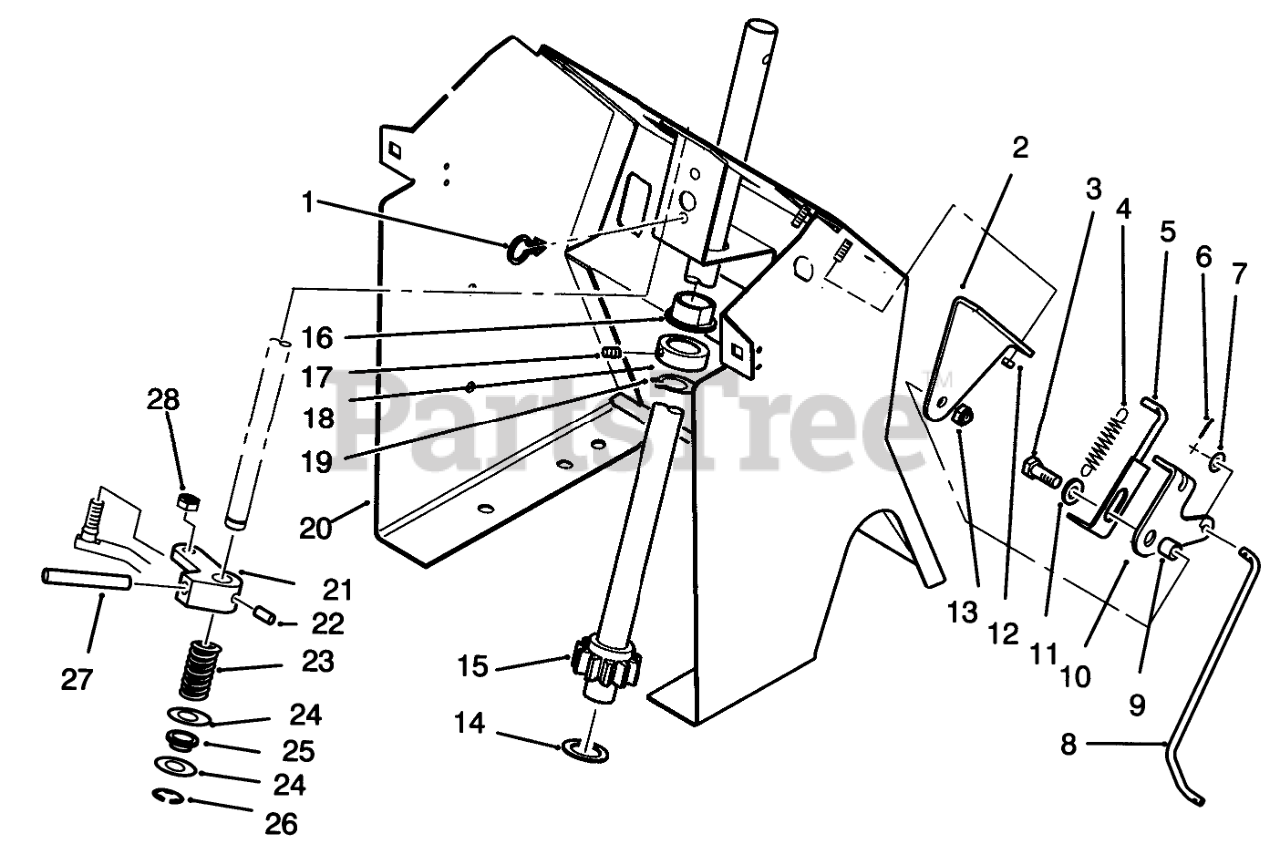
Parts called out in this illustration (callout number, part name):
1	CLIP-SNAP IN
2	SUPPORT-INDICATOR B
3	Bolt
4	SPRING-EXTENSION
5	WLDMT-INDICATOR R
6	Cotter Pin
7	WASHER-PLAIN
8	ROD-INDICATOR
9	SPACER
10	RETAINER-INDICATO B
11	WASHER-FLAT
12	Nut
13	NUT-LOCK, NI
14	WASHER
15	WLDMT-STRG SHAFT
16	BEARING-FLANGED
17	SCREW-HSH
18	COLLAR
19	RING-RETAINING
20	HOODSTAND W/A B
21	ARM-SPEED CONTROL
22	PIN-SPIROL 5/16X2.25
23	SPRING-COMPRESSION
24	SHIM-WASHER
25	BUSHING-NYLINER
26	RING-SHAFT, EXT
27	PIN-SPIROL 5/16X2.25
28	NUT-LOCK
